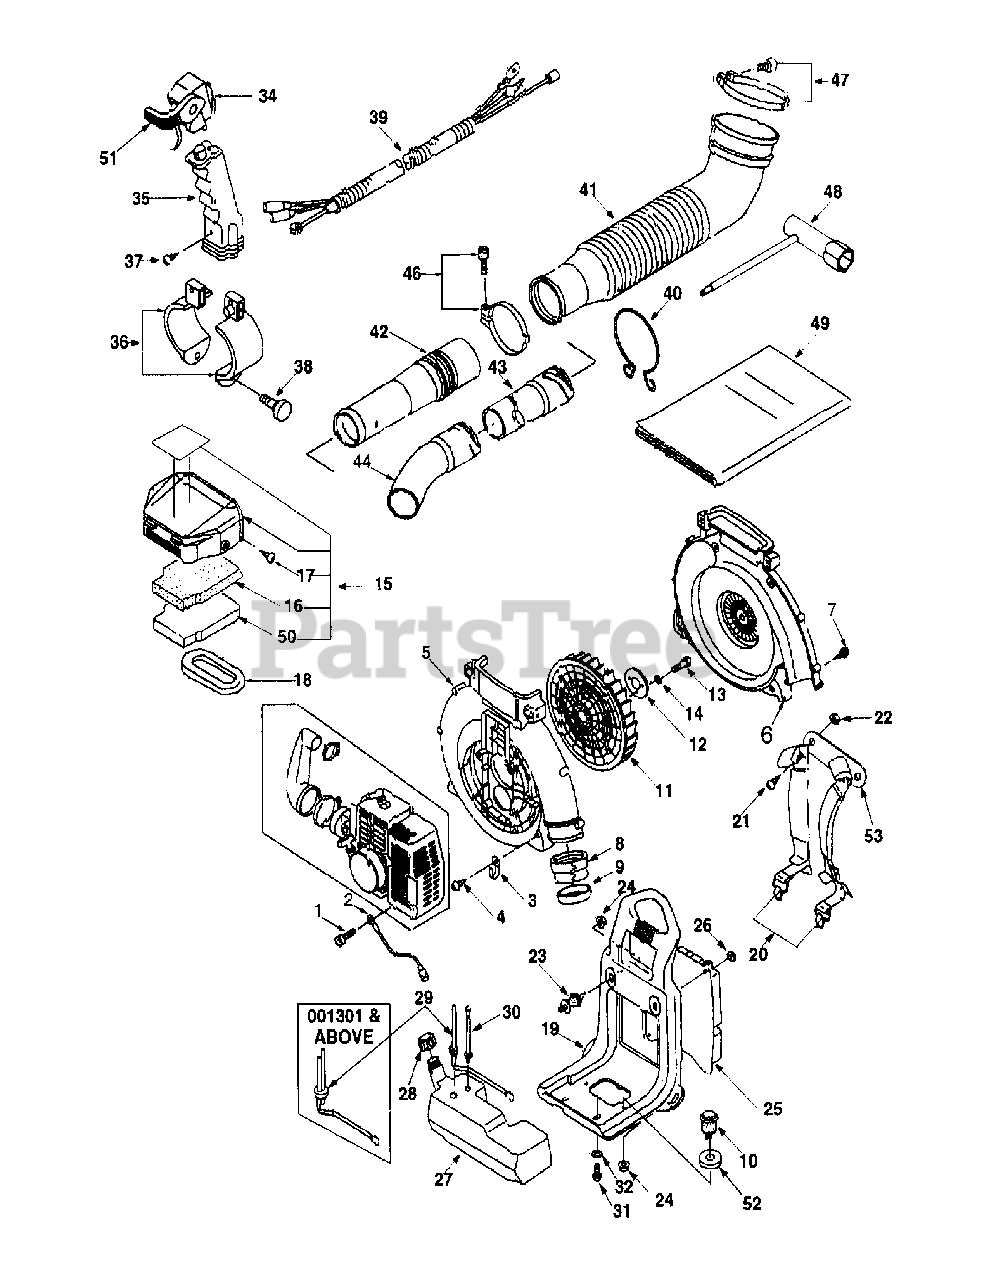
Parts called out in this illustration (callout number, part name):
1	Bolt, M6x30
2	Harness, Wire
4	Screw; M5x10
5	Casing, Compl(E)
6	Casing, Compl(S)
7	Screw; M5x25
10	Rubber Compl
11	Fan Compl
13	Bolt; M6x40-77
14	Spring Washer; M6
15	Silencer Ass'y, Air
16	Element(A), Air Filter
17	Screw; M6x15
19	Frame Compl
20	Harness Compl
21	Screw; M6x16
23	Rubber Compl
25	Cushion Compl
26	Fastener
27	Tank, Fuel
28	Cap Ass'y, Fuel Tank
29	Filter, Fuel
29	Filter Assy, Fuel
30	Valve Ass'y, Reversing
31	Screw; M5x14
32	Washer; 5.3x16x11.6
34	Lever, Throttle
36	Band Ass'y
37	Screw; M5x20
38	Bolt; M6x30
39	Wire Ass'y, Throttle
41	Pipe, Flexible
42	Pipe, Straight
43	Pipe, Straight
44	Pipe, Curve
46	Band Ass'y
47	Band Ass'y
48	Spanner, Box
49	Instruction Book
50	Element(B), Air Filter
